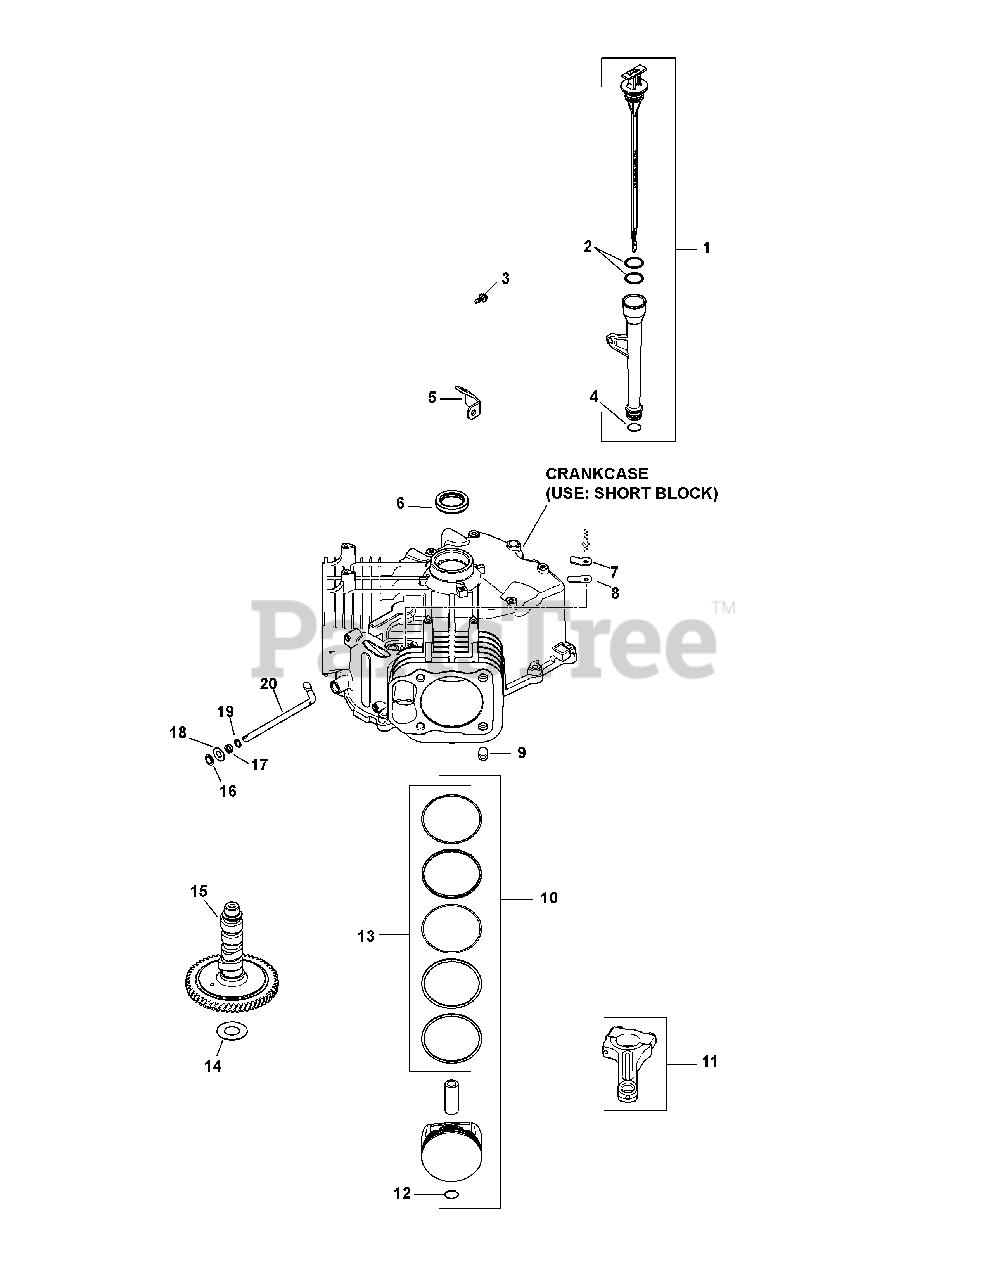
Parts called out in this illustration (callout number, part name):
1	Kit, Dipstick And Tube
3	Screw, Flg Thd Frm M5X0.8X13
4	O-Ring, Lower Oil Fill Tube
5	Bracket, Oil Fill Tube
6	Seal, Oil (Helix Lip)
7	Retainer, Breather Reed
8	Reed, Breather
9	Pin, Locating
10	Kit, Piston W/Ring (Std)
11	Rod, Assembly Connecting (Std)
12	Retainer, Piston Pin
13	Ring Set, Piston (Std)
14	Shim, Camshaft (White .028'')
14	Shim, Camshaft (Blue .03'')
14	Shim, Camshaft (Red .032'')
14	Shim, Camshaft (Yellow .034'')
14	Shim, Camshaft (Green .036'')
14	Shim, Camshaft (Gray .038'')
14	Shim, Camshaft (Black .04'')
15	Camshaft Assembly
16	Retainer, Ring
17	Seal, Governor Cross Shaft
18	Washer, Flat 9 Mm
19	Washer, Flat 11/32''
20	Shaft, Governor Cross
